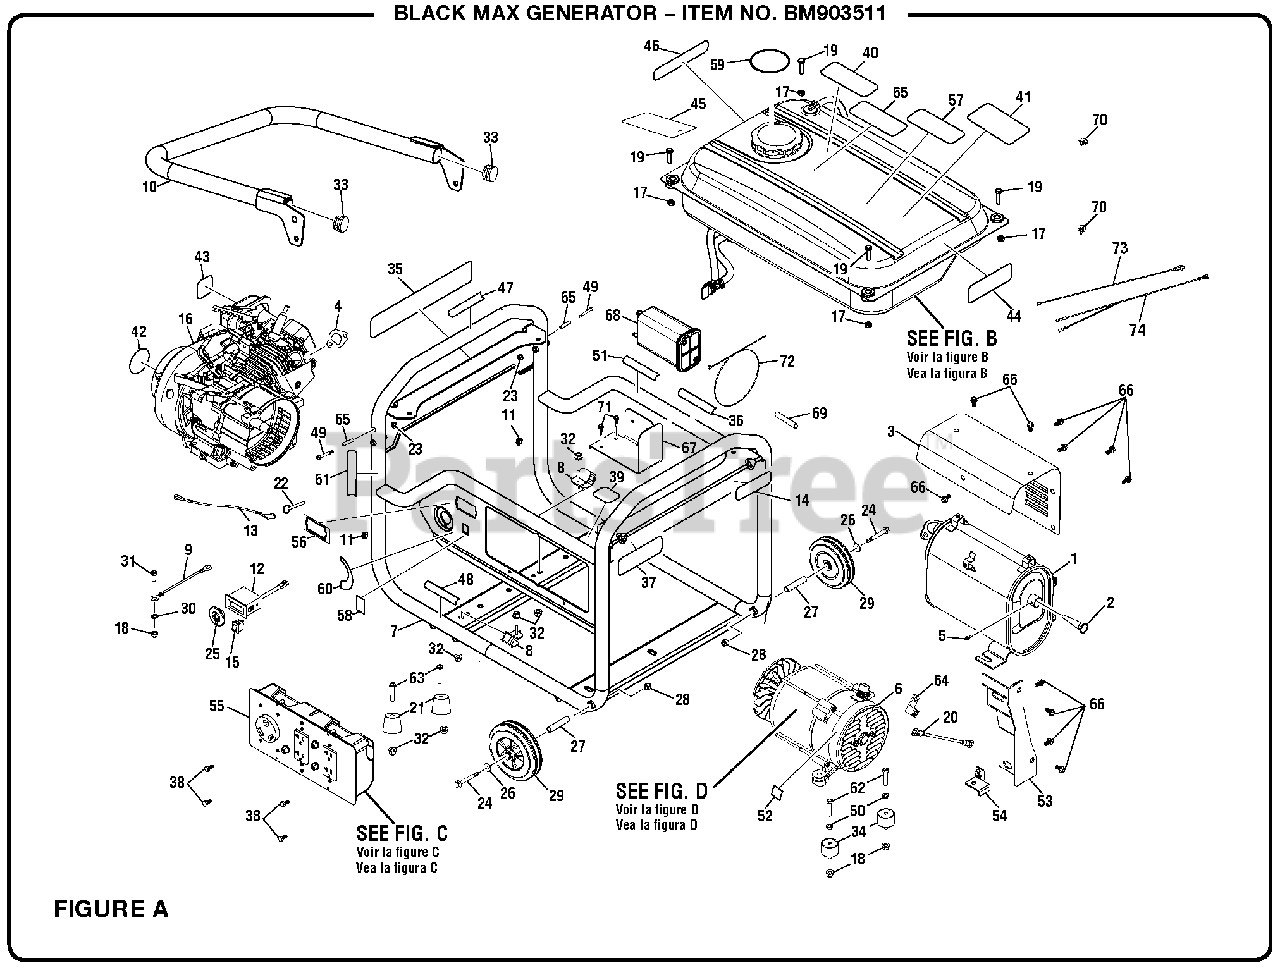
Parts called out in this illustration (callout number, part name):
2	Spark Screen
3	Heat Shield
4	Exhaust Gasket
5	Set Screw (Spark Arrestor)
6	Generator Head Assembly (See Figure D)
7	Carrier Assembly
8	Isolators (45deg)
9	Ground Wire Assembly
11	Handle Bumper
12	Digital Display
14	Fire Distance Label
15	Momentary Stop Switch
17	Lock Nut (M6)
18	Lock Nut (5/16-18)
19	Bolt (M6 x 20 mm, Hex Hd.)
20	Bonding Wire
21	Foot Assembly
23	Lock Nut (1/4-20)
24	Bolt (3/8-16 x 4-1/4 in.)
25	Fuel Valve Bezel
26	Washer (3/8 in.)
28	Lock Nut (3/8-16)
29	Wheel (7 in.)
30	Star Washer (5/16 in.)
31	Bolt (5/16-18 x .75 in.)
32	Flange Nut (M8)
34	Isolator (Generator)
35	Logo Label
36	Hot Surface Label
37	Combustion Label (Eng/Sp)
38	Screw (#6-20 x .38 in., Pan Hd.)
39	Data Label
40	E85 Label
41	CPSC Label
42	Recoil Housing Label
43	Choke Label
44	Ground Warning Label
45	Danger Hang Tag
46	Engine Start Label
47	Fire Danger Label
48	Lubricant Label
49	Bolt (1/4-20 x 1.5 in., Hex Hd.)
50	Lock Washer (5/16 in.)
51	Inquiries Label
52	Ground Label
53	Mounting Bracket (Left)
54	Mounting Bracket (Right)
55	Control Panel Assembly (See Figure C)
56	Hour Meter Label
57	Icon Label
58	On/Off Label
59	Fuel Stabilizer Label (English)
60	Fuel Valve Label
61	Lock Pin Label
62	Bolt (5/16-18 x 1.5 in., Hex Hd.)
63	Bolt (M8 x 1.25 in., Flange Hex Hd.)
64	Ground Lug
65	Fuel Stabilizer Label (Spanish)
66	Bolt (M8 x 1.25 in., Flange Hex Hd.)
67	Carbon Cannister Bracket
68	Carbon Cannister
69	Purge Hose (180 mm)
70	Hose Clamp (7/16 in.)
71	Screw (#10-16 x .75 in.)
72	Cable Tie
73	Switch Lead (Black)
74	Switch Lead Assembly (Green)
